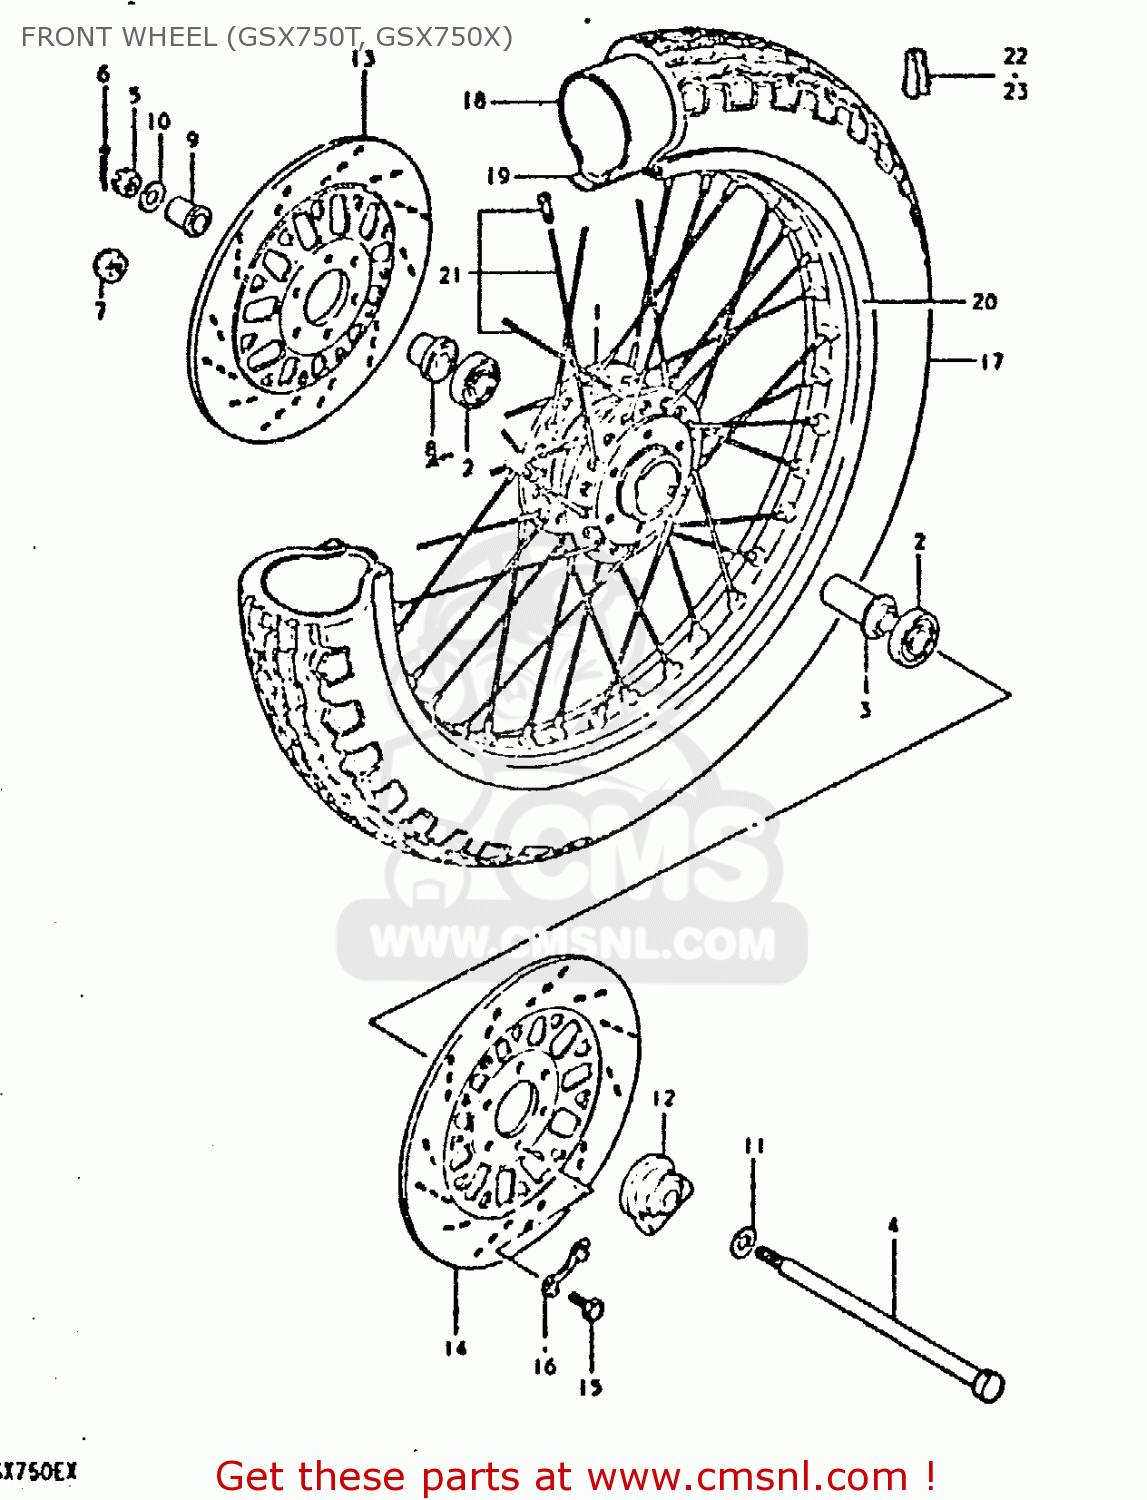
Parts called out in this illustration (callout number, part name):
1	DRUM,FRONT HUB
2	BEARING
3	SPACER,FR HUB BEARING
4	AXLE,FR
5	NUT 12MM
6	COTTER PIN
8	SPACER,FR AXLE,R
9	SPACER
10	WASHER
11	WASHER(15.5X26X2.3)
12	BOX ASSY,SPEEDOMETER GEAR
13	DISC,FR BRAKE,R
14	DISC,FR BRAKE,L
15	BOLT(8X25)
16	WASHER
17	TIRE,FRONT
18	TUBE,INNER
19	PROTECTOR,WHL INR TUBE
20	RIM,FR WHEEL
21	SPOKE SET,FRONT
22	BALANCER,WHEEL (B)
23	BALANCER,WHEEL (30G)
